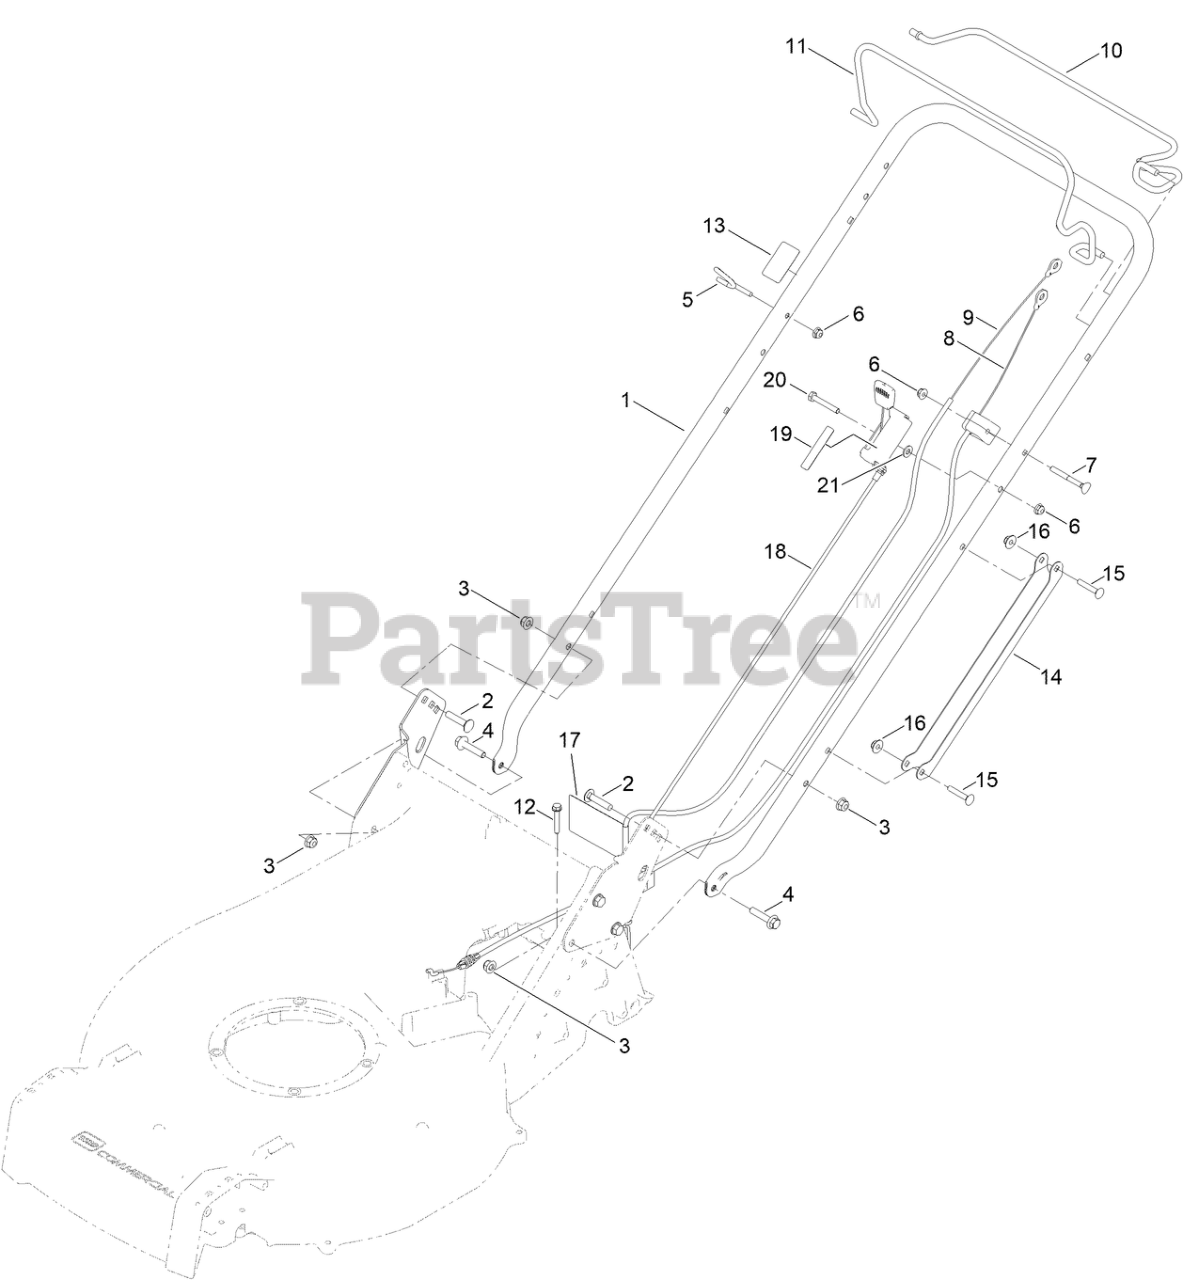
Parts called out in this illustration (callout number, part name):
2	BOLT-CARR
3	NUT-HF, NI
4	SCREW-HHF
5	GUIDE-ROPE
6	NUT-HF
7	SCREW-HANDLE
8	CABLE-BRAKE, KOHLER
9	CABLE-TRACTION
10	BAIL-TRACTION
11	BAIL-BRAKE
12	SCREW-HWH
13	DECAL-PRIMER
14	GUARD-CABLE, HANDLE
15	SCREW-CARR
16	NUT-HF
18	CONTROL-THROTTLE
19	DECAL-THROTTLE, CHOKE
20	SCREW-HH
21	WASHER-FLAT
